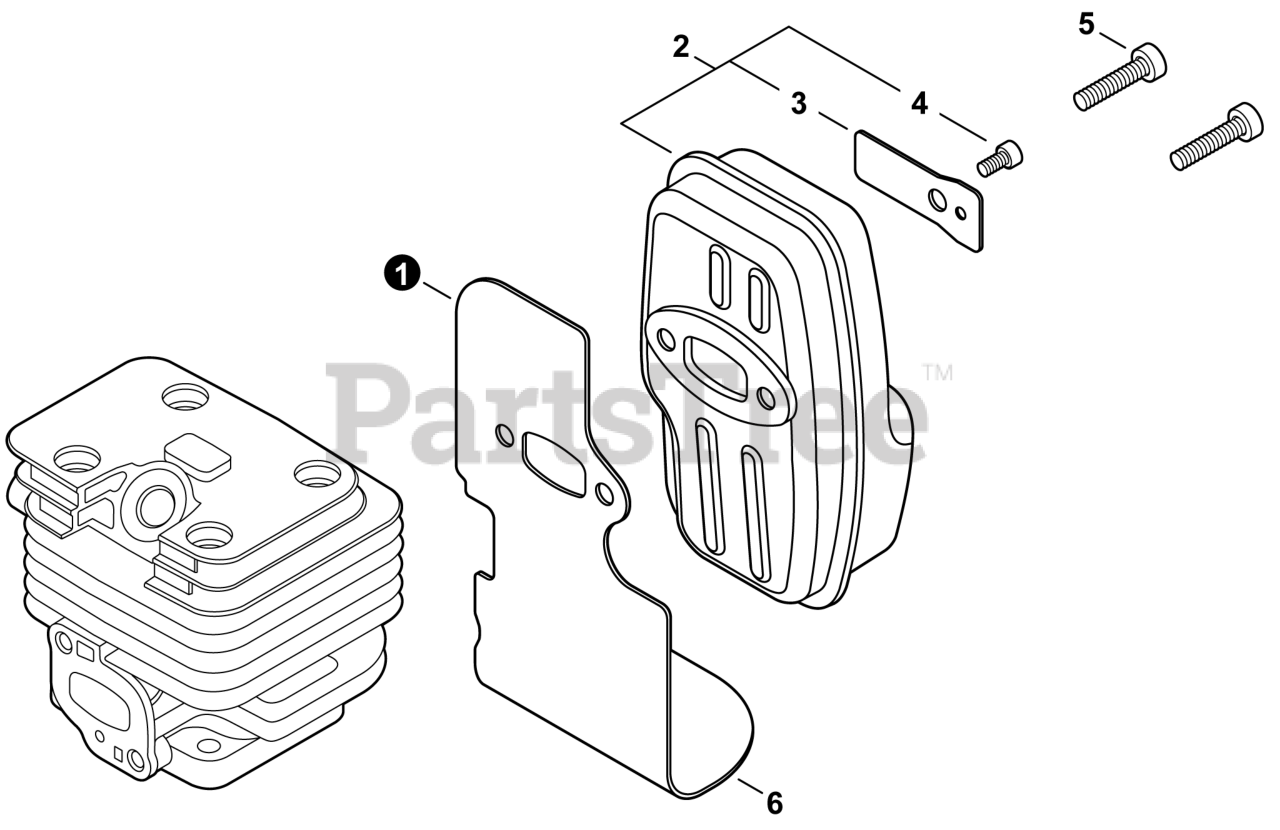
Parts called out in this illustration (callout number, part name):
1	HEAT SHIELD, EXHAUST
2	MUFFLER ASSY
3	SCREEN, SPARK ARRESTER
4	BOLT, TORX 4×8
5	BOLT, TORX 5×20
6	GASKET KIT
